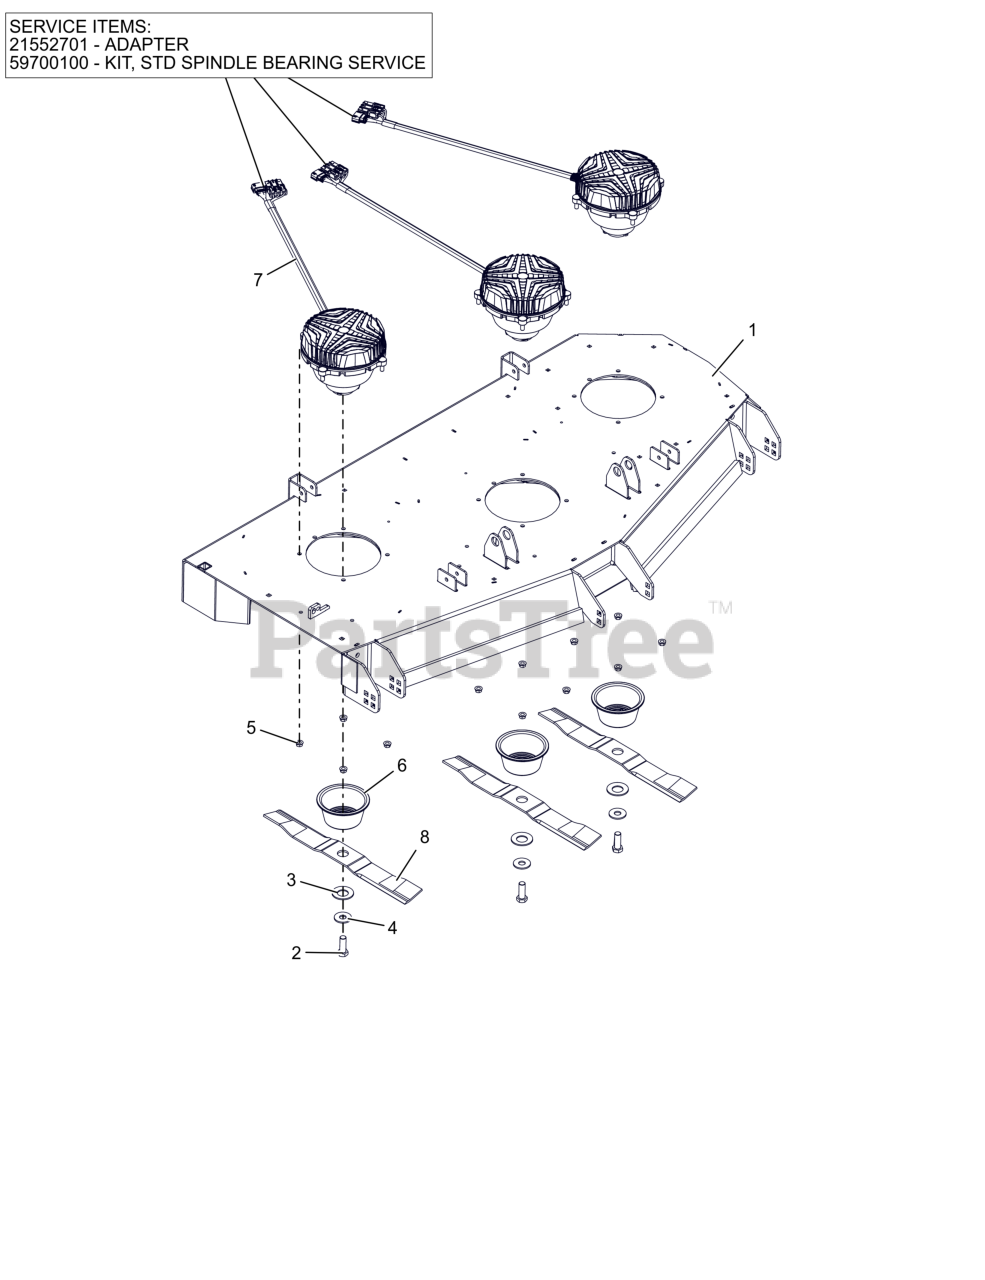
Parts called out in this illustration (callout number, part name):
1	WLDMT-60" PSEV SIDE DISCH DECK
2	BLT, HEX .62-18X1.75 G8 ZCC
3	WSHR, BLVL - .56X28.5X3 PHOS.COAT
4	WSHR, HRDN 0.687X1.75X0.134 HRD
5	NUT-LK-CTR-FLG .375-16 GF ZCC
6	GUARD, SPINDLE LOWER
7	MOTOR, SPINDLE-CW
7	ADAPTER
7	KIT, STD SPINDLE BEARING SERVICE
8	BLADE, MOWER 20.5"
